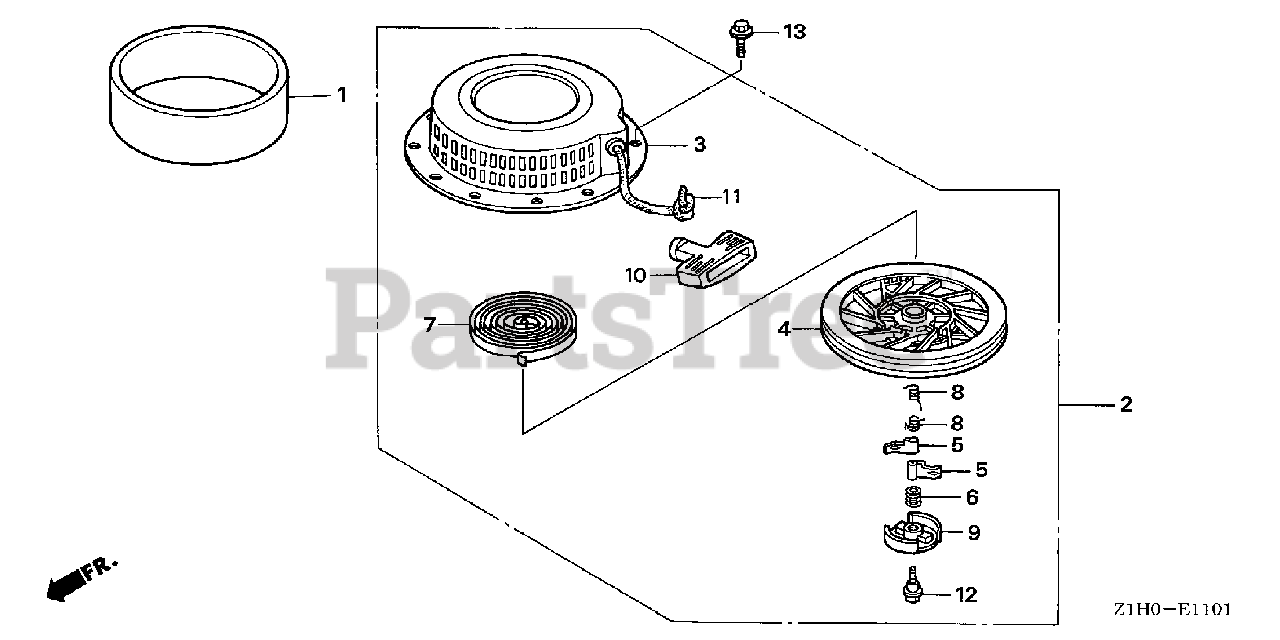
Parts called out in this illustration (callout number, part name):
1	FILTER, AIR
2	STARTER ASSY., RECOIL *R280* (POWER RED)
3	CASE, RECOIL STARTER *R280* (POWER RED)
4	PULLEY, RECOIL STARTER
5	RATCHET, STARTER
6	SPRING, FRICTION
7	SPRING, STARTER RETURN
8	SPRING, RATCHET
9	RETAINER, SPRING
10	GRIP, STARTER
11	ROPE, RECOIL STARTER
12	SCREW, CENTER
13	BOLT, FLANGE (6X10)
